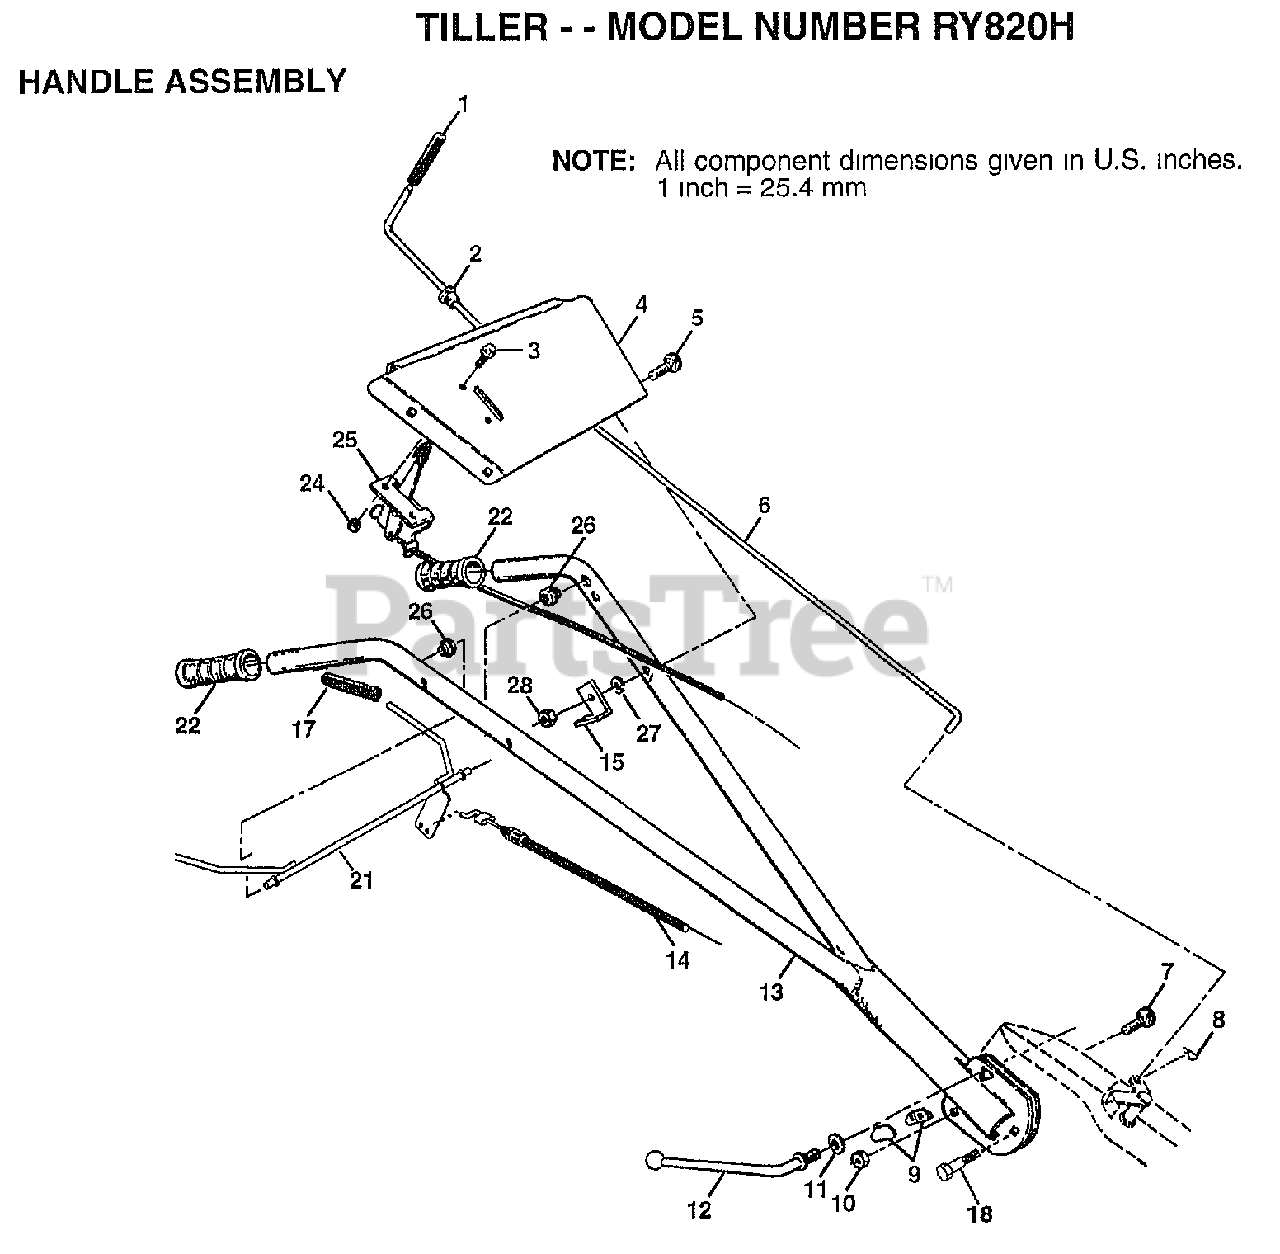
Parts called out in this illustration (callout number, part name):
1	GRIP TI
2	BUSHING
3	SCREW.PNHD.10-24
4	HANDLE BRACKET
5	BOLT CARRIAGE CRT
6	ROD SHIFT CRT
7	BOLT D
9	LOCK CRT
10	LOCKNUT
11	WASHER CRT
12	LEVER LOCK CRT
14	"CABLE, CLUTCH"
15	BRACKET.CLUTCH.CA
17	GRIP BAR CRT
18	BOLT PIVOT
21	BAR CONTROL
22	"GRIP,HANDLE"
25	"CONT,THROTTLE"
26	GROMMET.HANDLE.V-
27	LOCKWASHER
28	NUT
